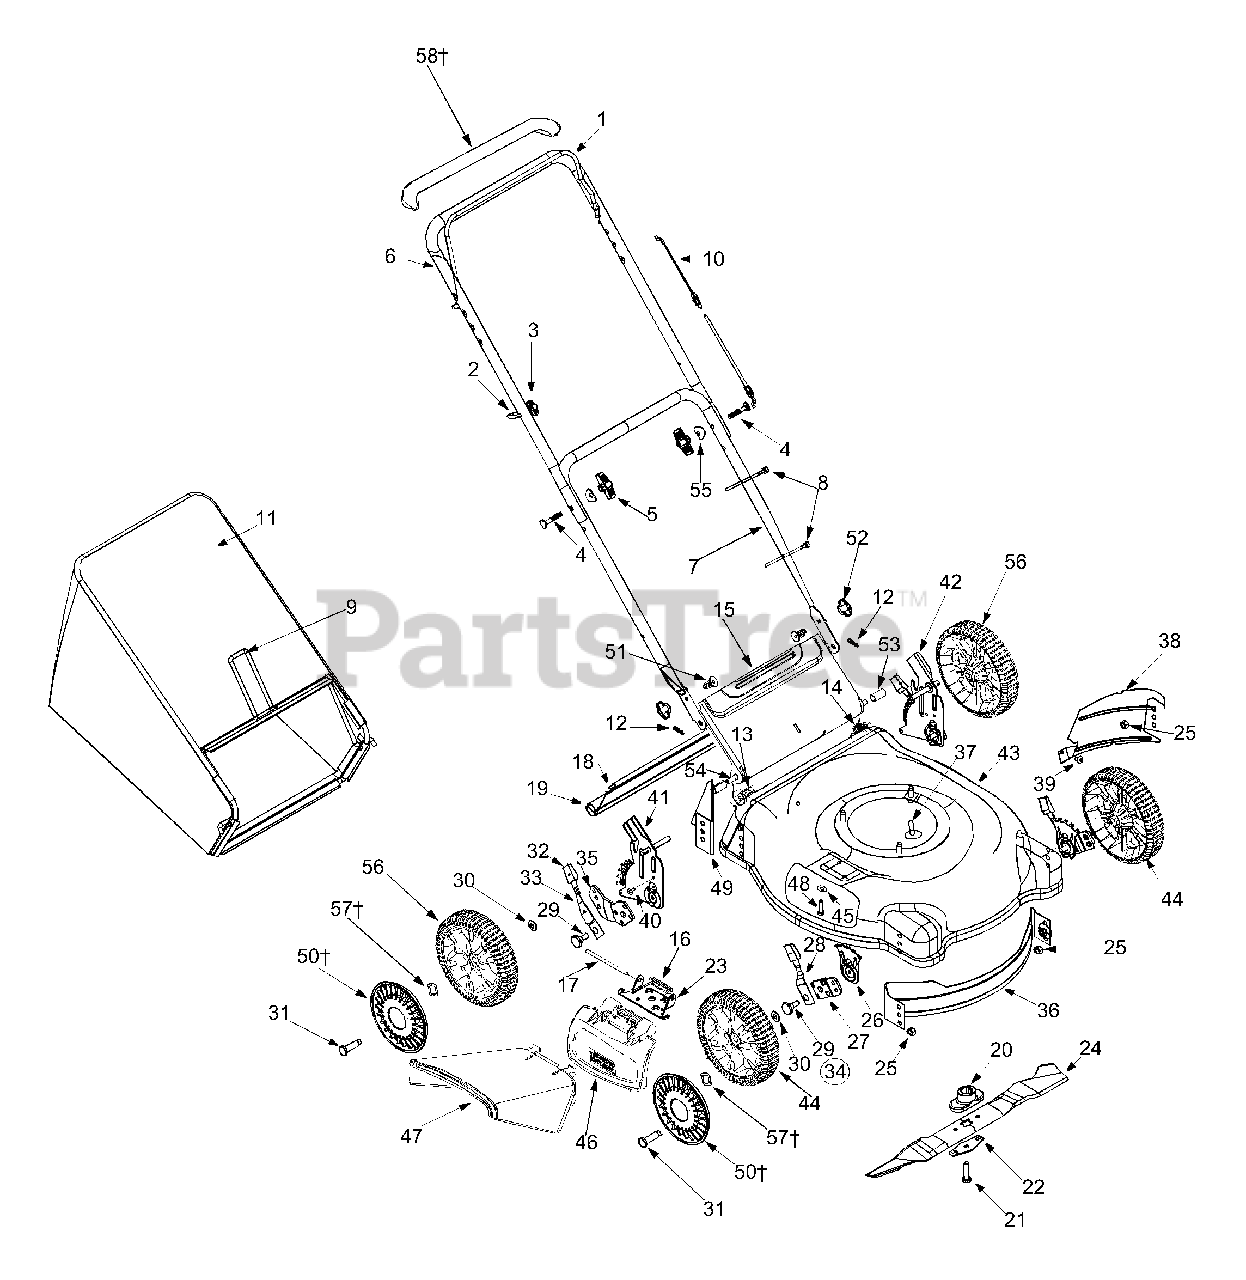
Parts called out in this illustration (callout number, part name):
2	Rope Guide
3	Handle Knob 1/4-20 Thd.
4	Curved Hd. Bolt 5/16-18 x 2"
5	Hand Knob
8	Cable Tie
10	Control Cable (Briggs & Stratton)
11	Grass Bag
12	Int. Cotter Pin 5/16" Dia.
13	Door Spring - R.H.
14	Door Spring - L.H.
15	Rear Discharge Door
16	Torsion Spring
17	Hinge Pin
18	Wire Rod
19	Rear Flap
20	Blade Adapter w/Star
21	Hex Bolt 3/8-24 x 1.5" Lg.
22	Blade Bell Support
23	Deflector Chute Adapter
24	21" Mulching Blade w/Star
25	Flange Nut 3/8-16 Thd.
26	Height Adj. Plate
28	Front Spring Lever
29	Shld. Bolt.5" Dia. x.357"
30	Bell Washer.38" I.D. x.88" O.D.
31	Axle Bolt
32	Spring Lever Knob
33	Rear Spring Lever
34	Height Adj. Assy. Comp. - RH
35	Pivot Bar R.H.
39	Torx Mach AB-Tap Scr. 1/4 x.62"
40	Hex Ind Wash. Scr. 1/4-14:.625
45	Bell Washer 1/4" I.D.
46	Hinged Mulching Plug
47	Chute Deflector: Side Discharge
48	Hex Hd Self-Tp Scr. 1/4-20 x.5"
50	Hub Cap - Radial Spoke Gray
51	Hex Carriage Screw 1/4-20
52	Wing Nut
53	Spacer,.375OD x.50ID
54	Rear Door Pivot Rod
55	Shoulder Washer
56	Rr. Wheel w/Bearings Black Link Thd.
57	Wave Washer
58	Bail Cover
